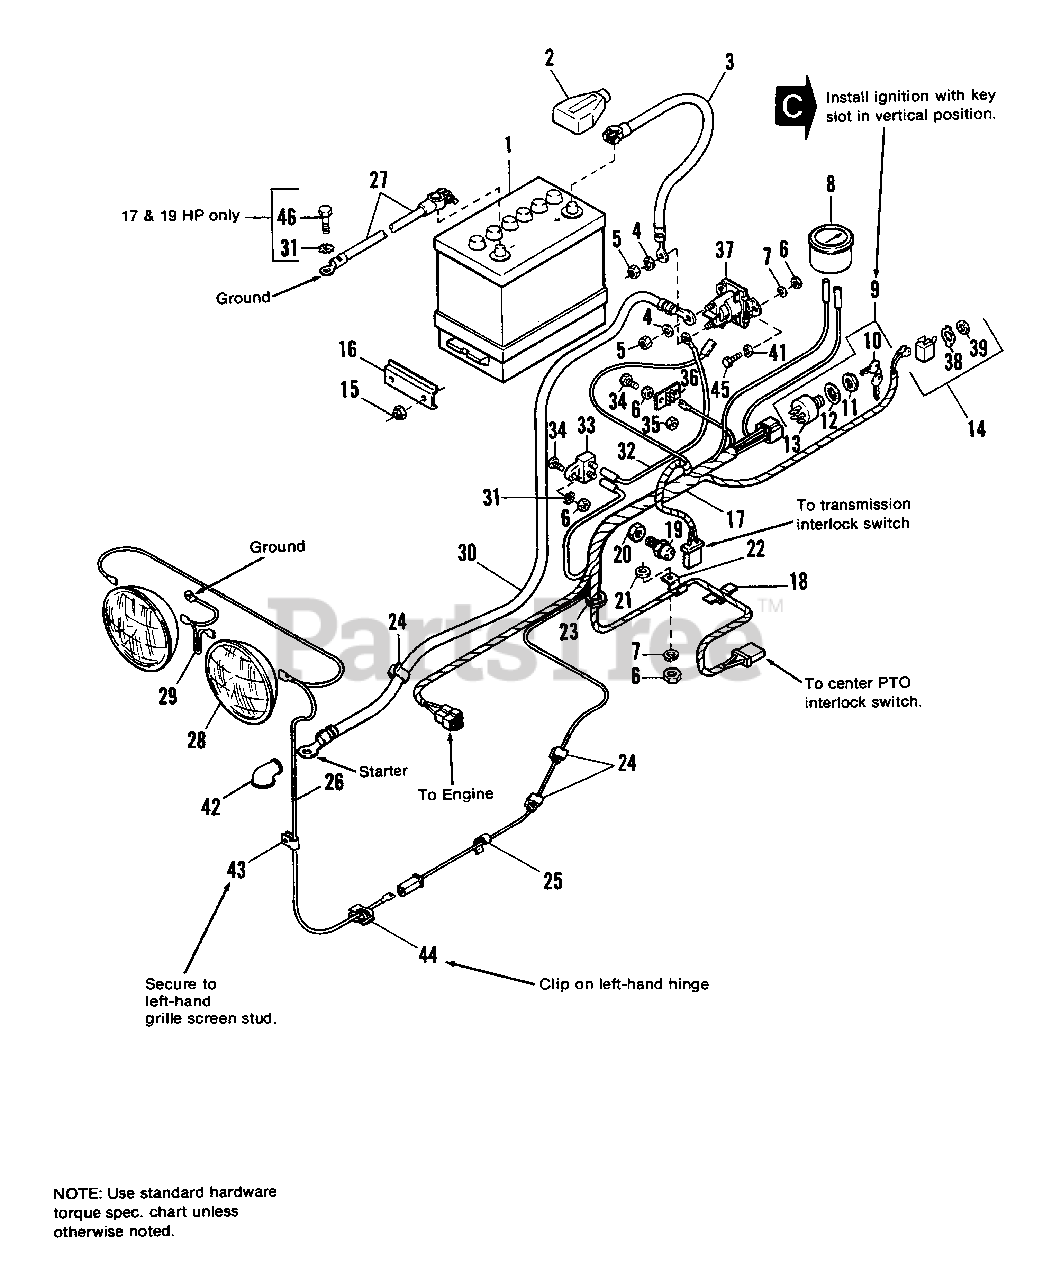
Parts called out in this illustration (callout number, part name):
1	BATTERY (Includes decal)
2	CABLE BOOT, Insulating
3	CABLE (Battery to Solenoid)
4	LOCKWASHER 5/16
5	NUT, Hex, Full, 5/16-18
6	NUT, Hex, Full, 1/4-20
7	LOCKWASHER, 1/4
9	SWITCH & KEY ASSY., Ignition
10	KEY SET (2)
11	NUT, Special
12	LOCKWASHER, Int., 5/8
14	SWITCH, Toggle
15	LOCKNUT, Hex, Esna, 5/16-18
17	HARNESS ASSY.
18	CLIP, Wire
19	SWITCH, Interlock
20	NUT, Pal
21	WASHER, Plain
22	CLIP, Cable
24	CLIP, Tinnerman
25	CLIP, Tinnerman
27	CABLE (Battery to Ground)
28	LAMP,Sealed Beam, G.E. #4411-1
29	WIRE ASSY.
30	CABLE (Solenoid to Starter)
31	LOCKWASHER, Ext., 1/4 (Qty. 1 on 7112 & 7114)
33	BREAKER, Circuit
34	CAPSCREW, Hex Hd., 1/4-20 x 5/8
35	LOCKNUT, Hex, 1/4-20
36	BOARD, Terminal
37	SOLENOID, Starter
39	NUT, Switch
41	WASHER, Special
42	COVER, Terminal
43	CLAMP, Wire
44	CLIP, Speed Cable
45	CAPSCREW, Hex Hd., 1/4-20 x 3/4
46	CAPSCREW, Hex Hd., 1/4-20 x 1/2 (used on 7117 & 7119 only)
